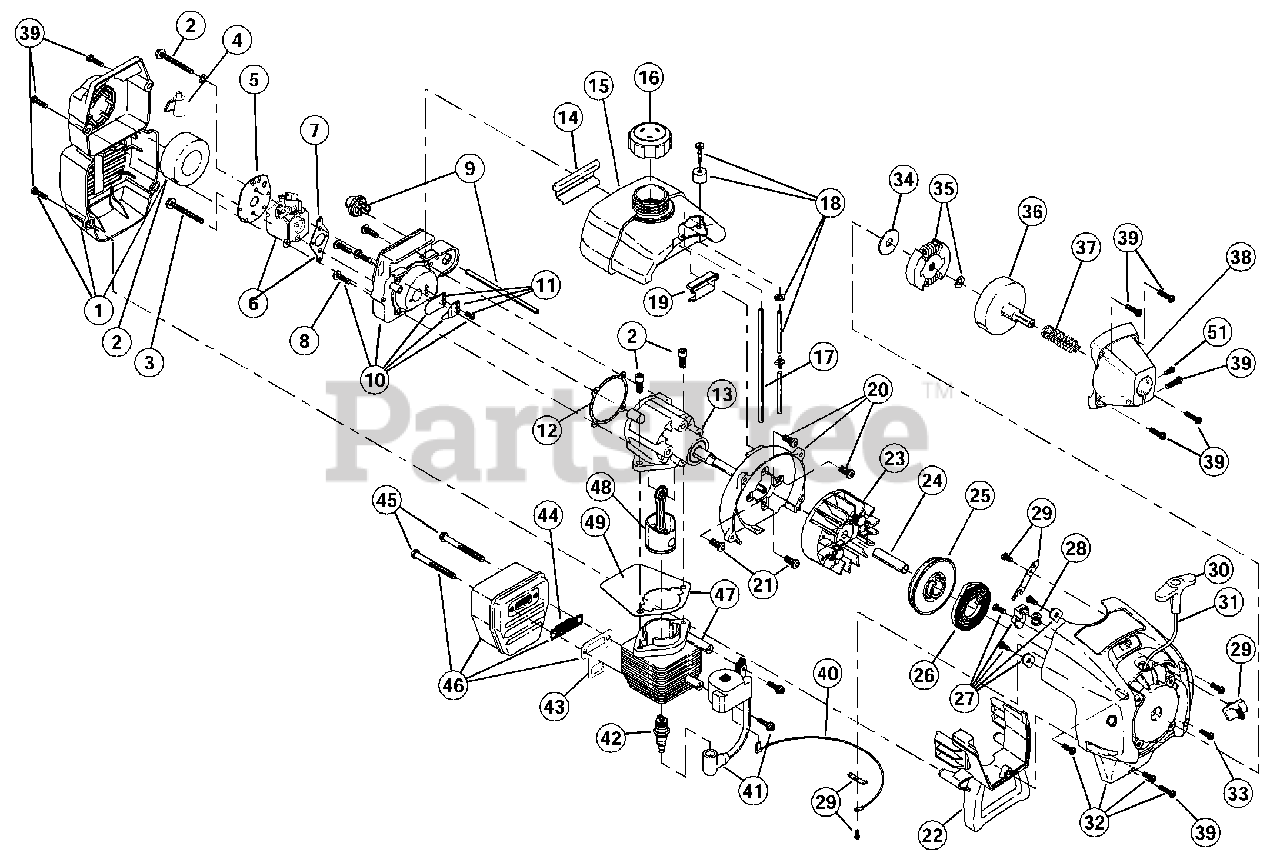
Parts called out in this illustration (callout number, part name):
1	Carburetor/Air Cleaner Cover Assembly
2	Air Cleaner Filter
3	Carburetor Mounting Screw Assembly
4	Choke Lever
5	Choke Plate
6	Carburetor Assembly
7	Carburetor Gasket
8	Carb Mount Screw
9	Primer and Hose Assembly
10	Carb Mount Assembly
11	Reed Assembly
12	Carburetor Mount Gasket
13	Crank Case Service Assembly
14	Rear Mounting Pad
15	Fuel Tank Assembly
16	Fuel Cap Assembly
17	Fuel Return Line
18	Fuel Line Assembly
19	Front Mounting Pad
20	Shroud Assembly
21	Shroud Screw
22	Shroud Extension and Stand
23	Flywheel Assembly
25	Recoil Pulley Assembly
26	Recoil Spring
27	Pulley Retainer Assembly
28	Rope Guide
29	Switch Assembly
30	Pull Handle
32	Starter Housing Assembly
33	Housing Screw
34	Clutch Washer
35	Clutch Rotor Assembly
36	Clutch Drum Assembly
38	Clutch Cover Assembly
40	Wire Lead
41	Module Assembly
42	Spark Plug
43	Exhaust Gasket
44	Spark Arrestor
45	Muffler Mounting Bolt Assembly
46	Muffler Assembly
47	Cylinder Assembly
48	Piston and Rod Assembly
49	Cylinder Gasket
50	Cylinder Bolt
51	Anti-Rotation Screw
